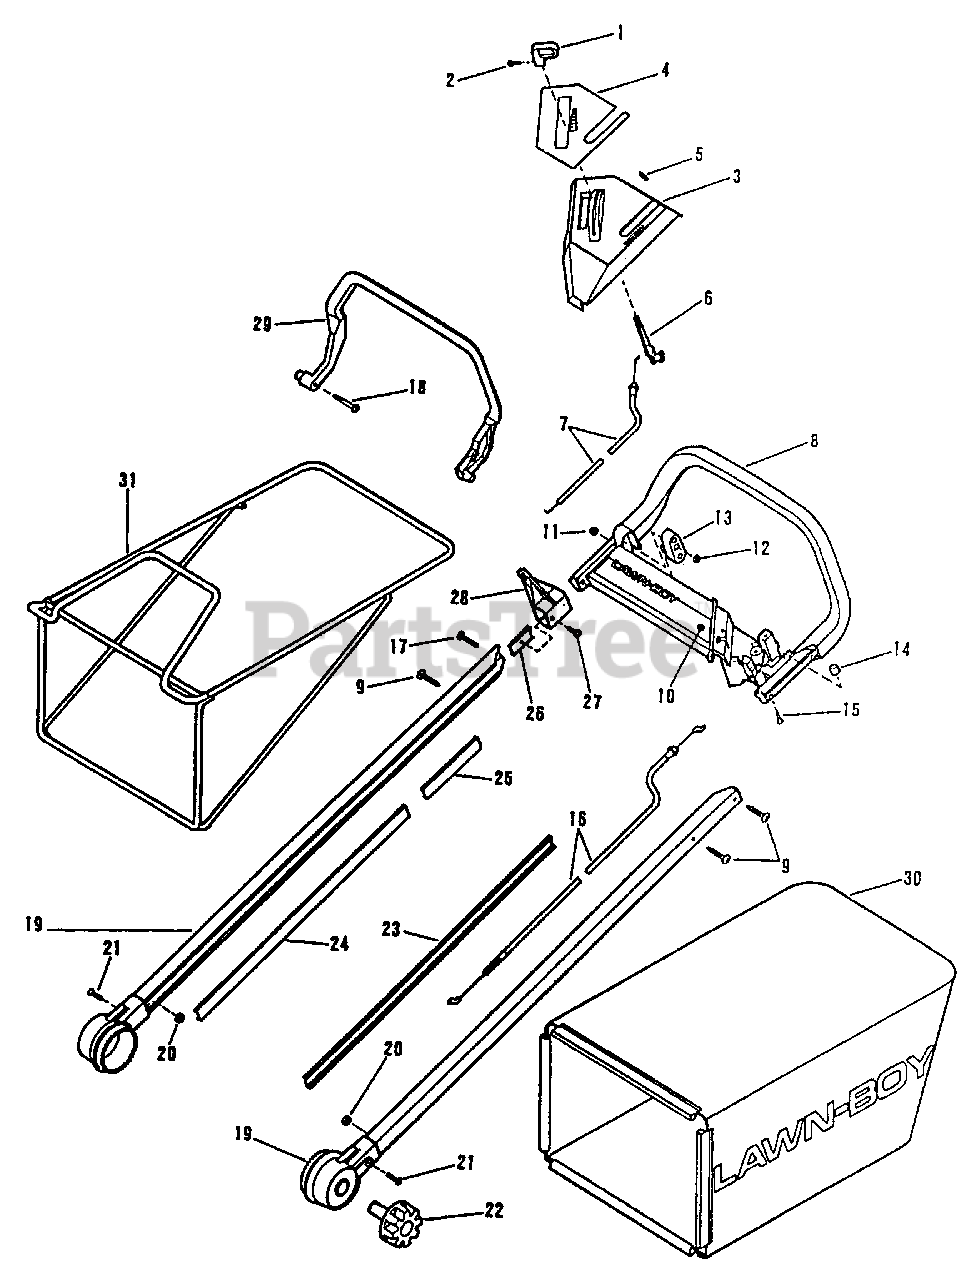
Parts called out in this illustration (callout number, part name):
1	Knob Assembly-Throttle
2	Set Screw
3	Upper Cover Assy (ZPRB)
4	Plate
5	Plug
6	Throttle Lever
7	Cable Assembly-Throttle
8	Handle and Decal Assembly
9	Screw-Thread Forming
10	Decal-Lawn-Boy
11	Nut
12	Locknut
13	Bail Block
14	Bumper
15	Screw
16	Cable Assembly-Engine Brake
17	Screw
18	Screw-Bail Pivot
19	Handle Knuckle and Extrusion
20	Nut
21	Screw
22	Knob-Handle Mounting
23	Handle Insert-Cable Side
24	Handle Insert
25	Handle Insert
26	Nut Plate
27	Screw
28	Rope Guide
29	Engine Brake Bail
30	Rear Grass Bag
31	Frame
